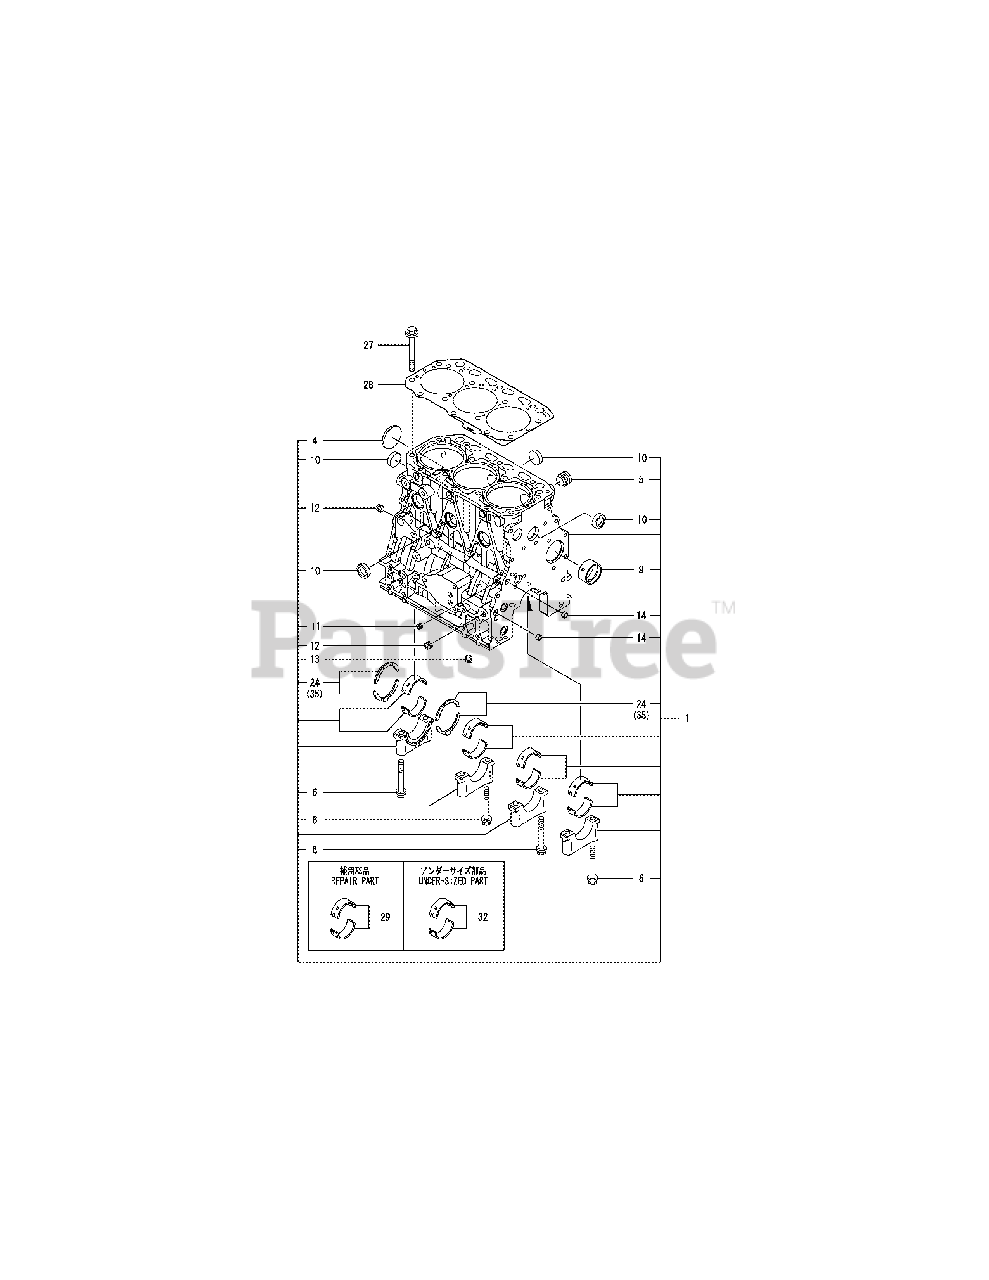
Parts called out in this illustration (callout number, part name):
1	BLOCK ASSY, CYLINDER
6	BOLT, METAL CAP
9	BUSH, CAMSHAFT A
24	METAL ASSY, THRUST
27	BOLT, CYLINDER HEAD
29	MAIN BEARING SET
32	MAIN METAL US=0.25
35	BEARING, THRUST.25OS
